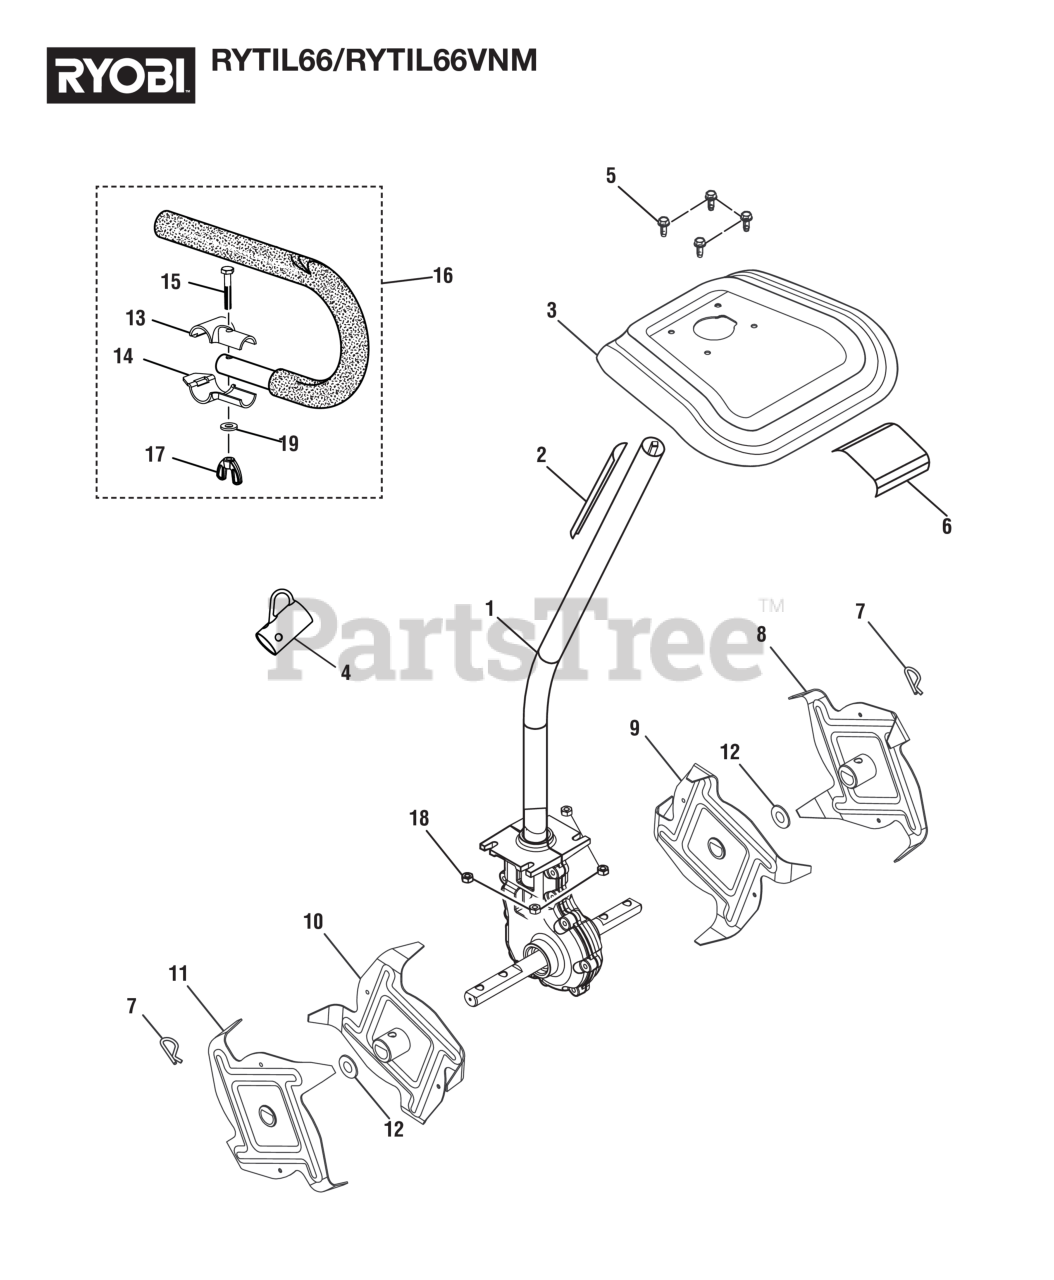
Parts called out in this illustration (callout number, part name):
1	Gear Case and Drive Shaft Assembly
2	Warning Label
3	Tine Shield Assembly
4	Storage Hanger Cap
5	Screw (1/4-20 x 5/8 in.)
6	Warning Label
7	Hitch Pin (3/4 in.)
8	Tine Assembly D
9	Tine Assembly C
10	Tine Assembly B
11	Tine Assembly A
12	FELT WASHER
13	Top "J" Handle Clamp
14	Bottom "J" Handle Clamp
15	Bolt (1/4-20 x 1-1/2 in., Hex Hd.)
16	"J" Handle and Grip
17	Wing Nut (1/4-20, Plastic)
18	LOCK NUT (1/4-20)
19	Washer (ID7.25 x OD16 x 1.5t)
